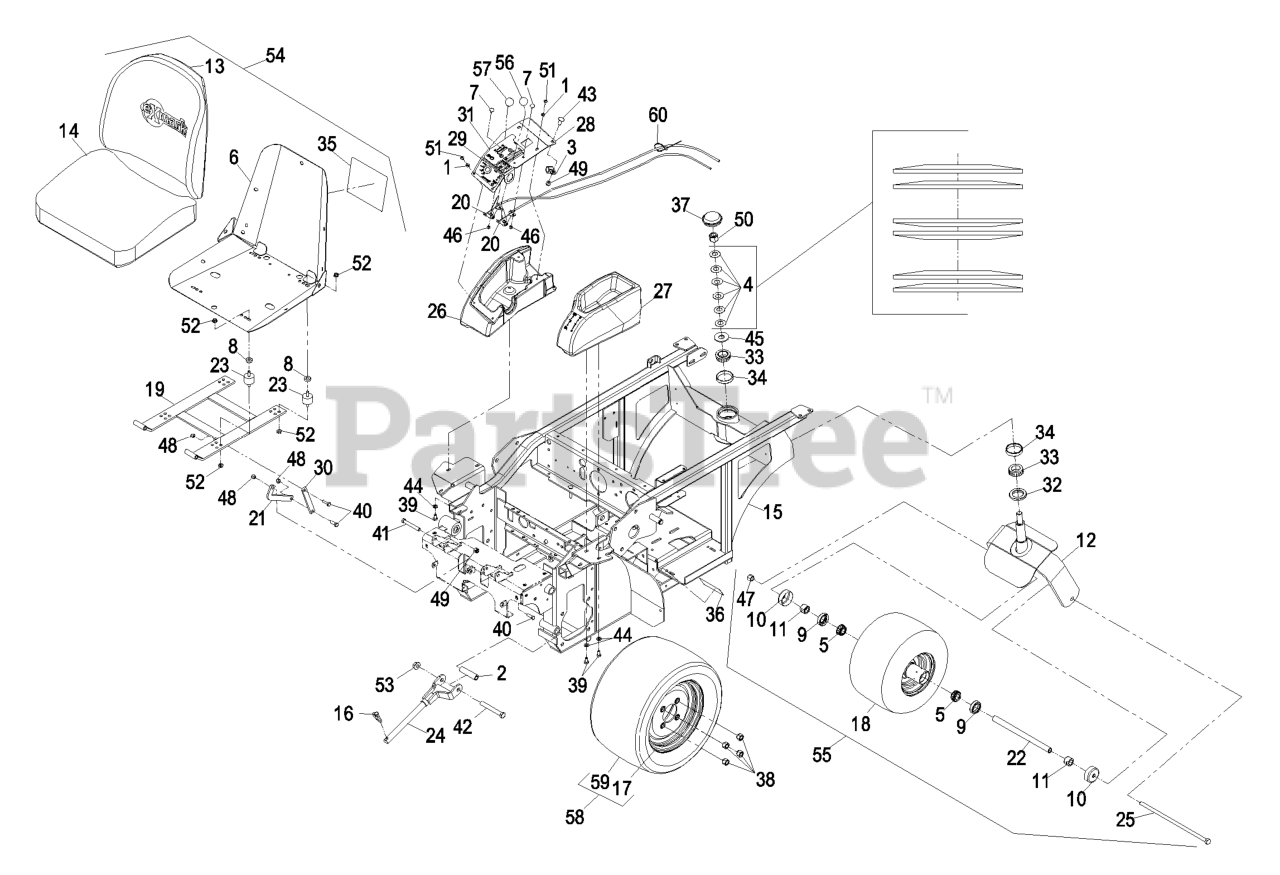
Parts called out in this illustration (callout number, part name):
1	WASHER-SPRING
2	SPACER-WHEEL, SHORT
3	CLIP-LOOM
4	WASHER-BELLVILLE
5	BEARING-CONE, TAPERED ROLLER
6	ASM,SEAT FRAME W/DECAL
7	BOLT-CARR
8	SPACER
9	SEAL-CASTER
10	GUARD-SEAL
11	SPACER-NUT
12	FORK-REAR CASTER
13	CUSHION,SEAT BACK
14	CUSHION,SEAT BOTTOM
16	PIN-LYNCH
17	ASM,WHEEL
19	FRAME-SEAT
20	CABLE,CONTROL 42"-ANGLED
21	LINK-SEAT STOP, LOWER
23	MOUNT-VIBRATION, RUBBER
25	SCREW-HH
28	ASM,INSTRUMENT PANEL W/DE
29	DECAL,IGNITION/SPEED CONT
30	LINK-SEAT
31	DECAL,INSTRUMENT PANEL
32	SEAL-GREASE
33	BEARING-ROLLER, CONE TAPE
34	CUP-TAPERED, ROLLER BEARI
36	DECAL,CLUTCH ADJUSTMENT
37	CAP-GREASE
38	NUT-LUG
39	SCREW-HH
40	SCREW-HH
41	SCREW-CARR
42	SCREW-HH
43	SCREW-CARR
44	WASHER-PLAIN
45	WASHER-FLAT
46	NUT-LOCK, NI
47	NUT-LOCK, NI
48	NUT-LOCK, NI
49	NUT-LOCK, NI
50	NUT-LOCK, NI
51	SCREW-PTH
53	NUT-HHF
54	Asm, Seat W/Decal
55	REAR CASTER WHEEL ASM
56	KNOB-BALL
57	KNOB-BALL, BLACK
58	ASM,WHEEL & TIRE
60	TIE-CABLE
